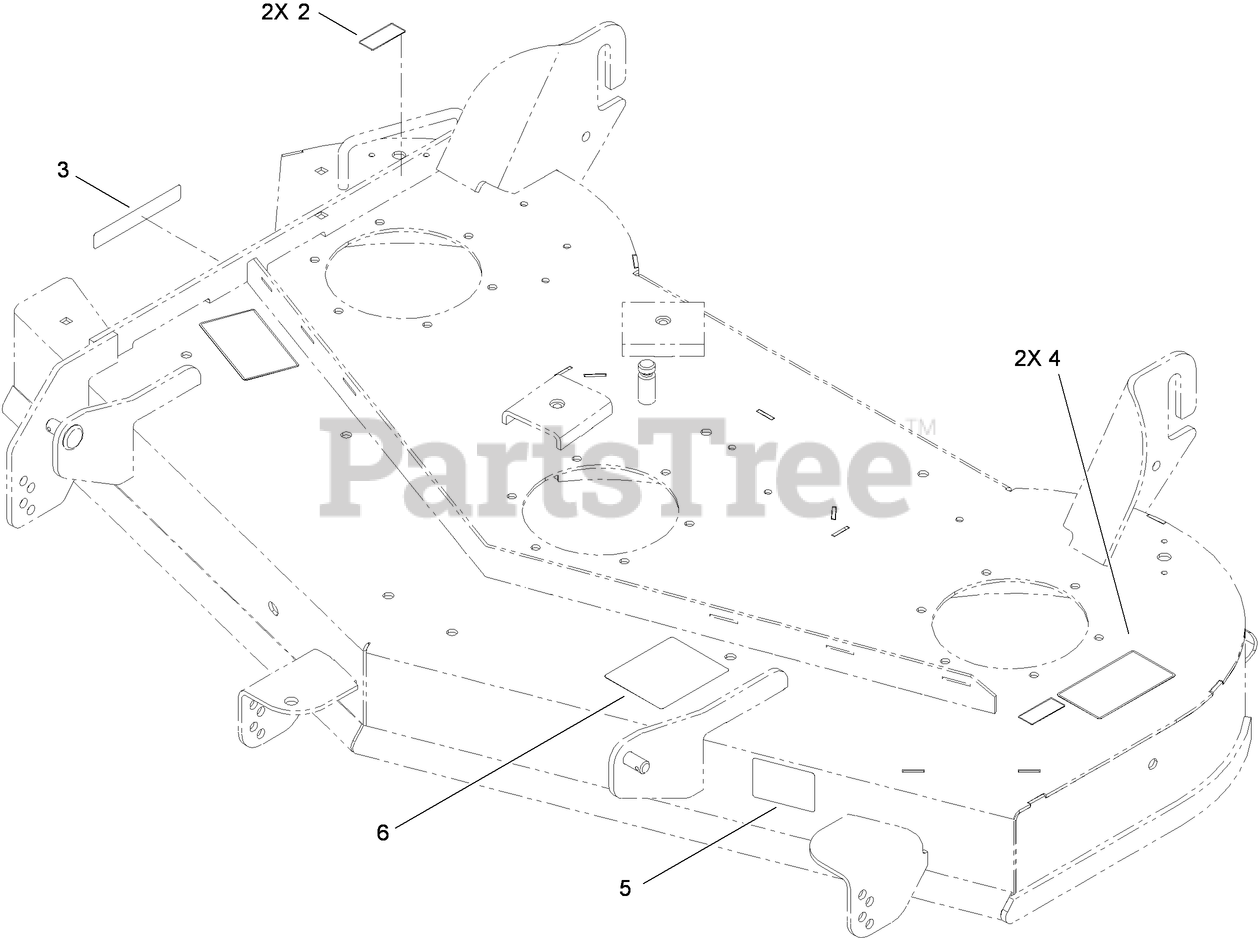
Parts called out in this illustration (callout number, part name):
2	DECAL-DANGER
3	DECAL-DANGER
4	DECAL-DANGER
5	DECAL-SCALP, ANTI
6	DECAL-ROUTING, BELT
